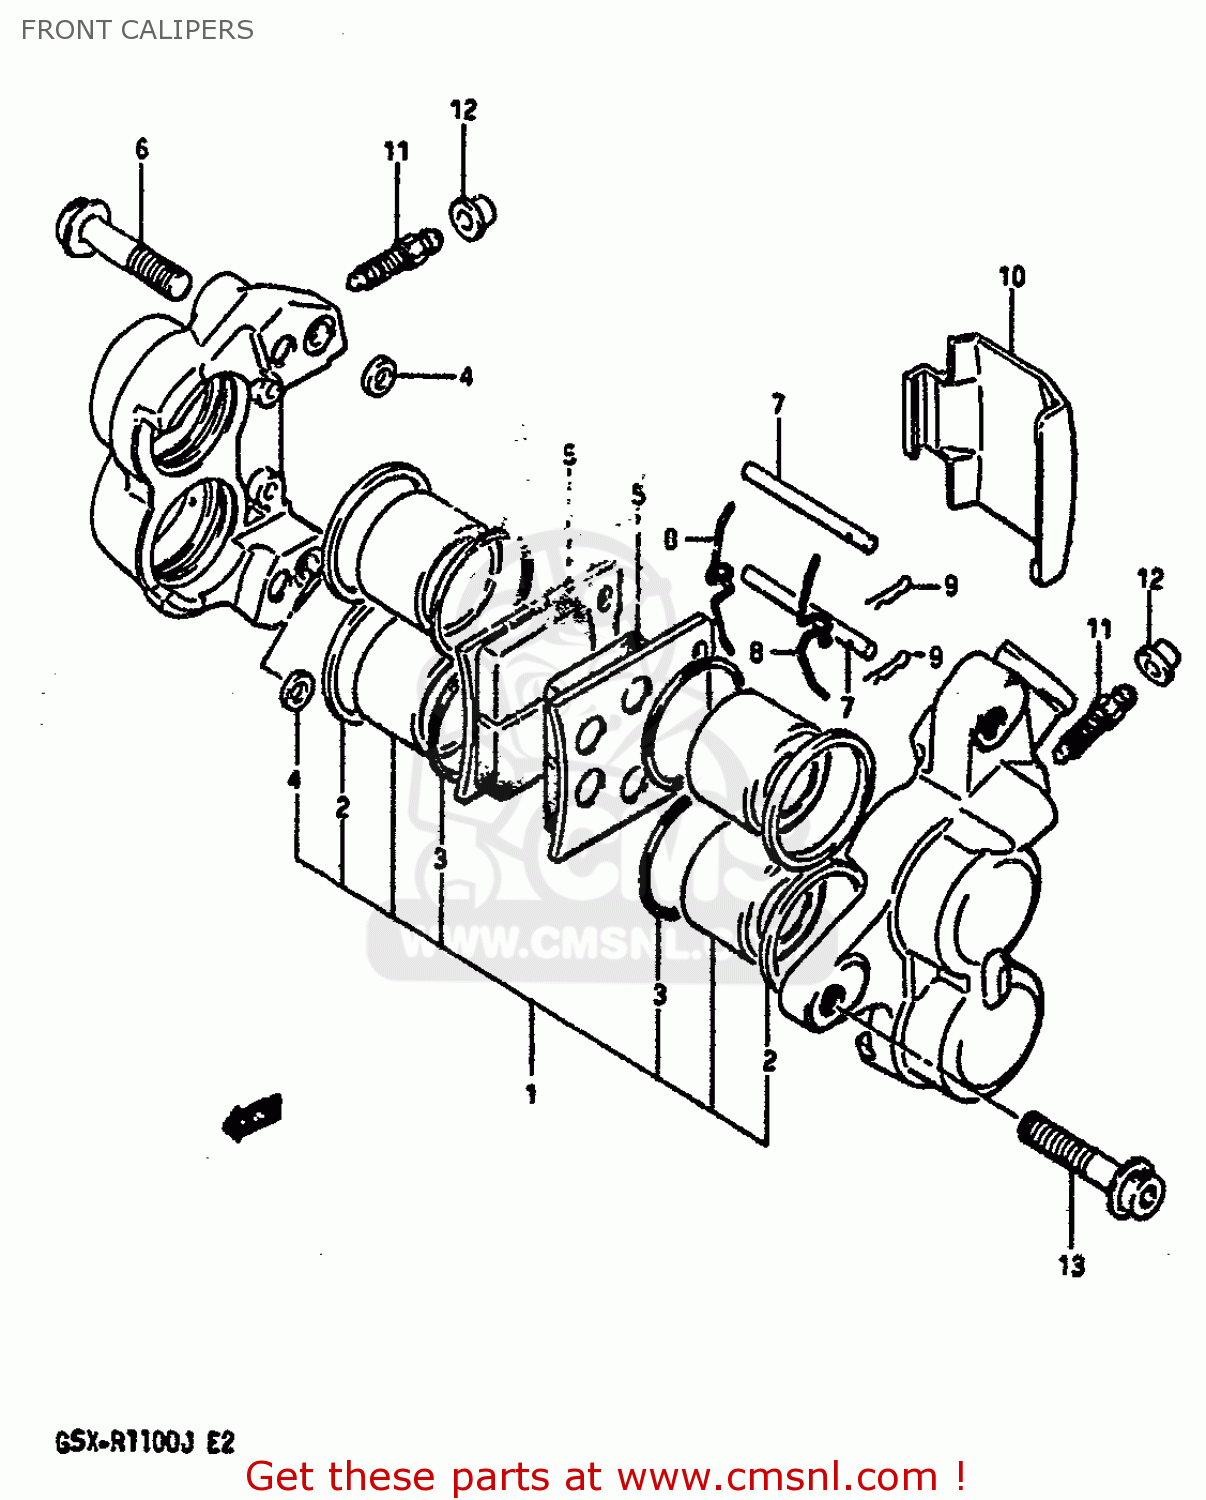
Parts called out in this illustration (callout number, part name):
1	PISTON SET
2	SEAL,PISTON
3	SEAL,WIPER
4	SEAL,JOINT
5	PAD
6	BOLT,HOUSING
7	PIN,PAD
8	SPRING
9	CLIP,PAD PIN
10	COVER,CALIPER
11	BLEEDER
12	CAP,BREATHER
13	BOLT
